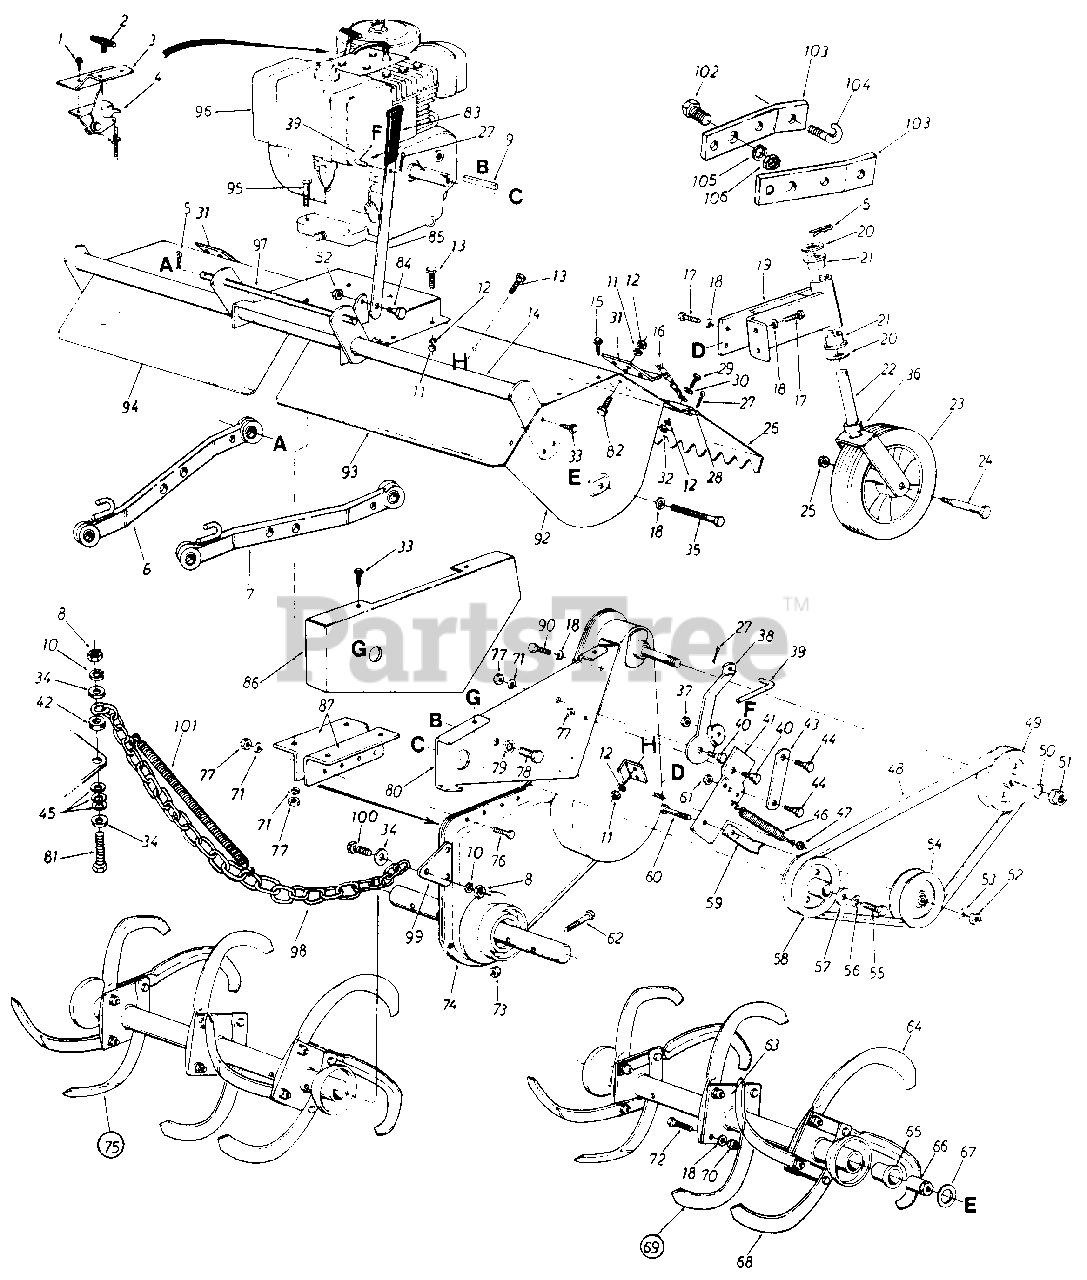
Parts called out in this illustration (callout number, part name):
1	Hex Wash. Hd. Self-Tap Scr. #8 x .50" Lg.
2	Throttle Control Knob -
3	Throttle Control Bracket
4	Throttle Control Ass'y. Comp.
5	Internal Cotter Pin
6	Draft Bar Ass'y.- R.H.
7	Draft Bar Ass'y.- L.H.
8	Hex Nut 3/8-24 Thd."
9	Sq. Key 1/4" x 1/4" x 2.00" Lg.
10	L-Wash. 3/8" I.D.
11	Hex Nut 1/4-28 Thd.
12	L-Wash. 1/4" I.D.
13	Hex Bolt 1/4-28 x .62" Lg.
16	72 Dog Chain x 20" Lg.
17	Hex Wash. Hd. Self-Tap Scr. 3/8-24 x .75" Lg.
18	L-Wash. 3/8" I.D.
21	Flange Bearing 1/4" I.D. x 1.00" O.D.
24	Shoulder Bolt .623" I.D. x 3.62" Lg.
25	Hex Cent. L-Nut 7/16-14 Thd.
28	L.H. Flap Rod
29	Hex Bolt 1/4-20 x .62" Lg.
30	Fl-Wash. 1/4" I.D.
33	Hex Wash. Hd. Self-Tap Scr. 1/4" x .62" Lg.
34	Fl-Wash..385" I.D. x 1.0" O.D. x .135 Thk.
35	Hex Bolt 3/8-16 x 1.25" Lg.
36	Spacer .752" I.D. x 1.25" O.D.
37	Hex Cent. L-Nut 5/16-18 Thd.
40	Shoulder Bolt 7/16" Dia. x 1.75" Lg.
45	Fl-Wash..406" I.D. x .74" O.D. x .063 Thk.
46	Extension Spring .62" O.D. x 6.12" Lg.
47	Hex Crown Nut 3/8-24 Thd.
48	"V"-Belt 1/2" x 43" Lg. (Kevlar)
49	1/2" "V"-Pulley 4.75" O.D. x .625" Bore
50	L-Wash. 5/8" I.D."
51	Hex Ins. L-Nut 5/8-18 Thd.
52	Hex Cent. L-Nut 3/8-16 Thd.
53	Fl-Wash. 3/8" I.D.
54	Idler Pulley 4.0" O.D.
55	Hex Bolt
56	L-Wash. 7/16" I.D.
57	Fl-Wash. 7/16" I.D. x 1.38" O.D.
58	1/2" "V"-Pulley .475" O.D. x 1.00" Bore
61	Hex Cent. L-Nut 5/16-18 Thd.
62	Hex Bolt 7/16-14 x 2.00" Lg.
66	Spacer
67	Thrust Wash. 1/2" I.D. x 1.55" O.D.
71	L-Wash. 5/16" I.D.
72	Hex Bolt 3/8-24 x 1.5" Lg.
73	Hex Cent. L-Nut 7/16-14 Thd.
77	Hex Nut 5/16-18 Thd.
78	Hex Bolt 1/2-20 x .88" Lg. (Grade 5)
79	L-Wash. 1/2" I.D.
80	Clutch Support Bracket
81	Hex Bolt 3/8-24 x 1.75" Lg.
82	Hex Bolt 1/4-28 x .75" Lg.
83	Plastic Grip
84	Shoulder Bolt .498 Dia. x .212 Lg.
85	Clutch Handle
96	8 H.P. Engine
97	Tiller Mounting Shaft 16" Lg.
98	Chain 23" Lg.
99	Tiller Mounting Bracket
100	Hex Bolt 3/8-24 x 1.25" Lg.
101	Extension Spring
102	Hex Bolt 5/8-18 x 1.62"
103	Drag Link Extension
104	Hitch Chain Hook
105	L-Wash. 5/8" I.D.
106	Hex Jam Nut 5/8-18 Thd.
